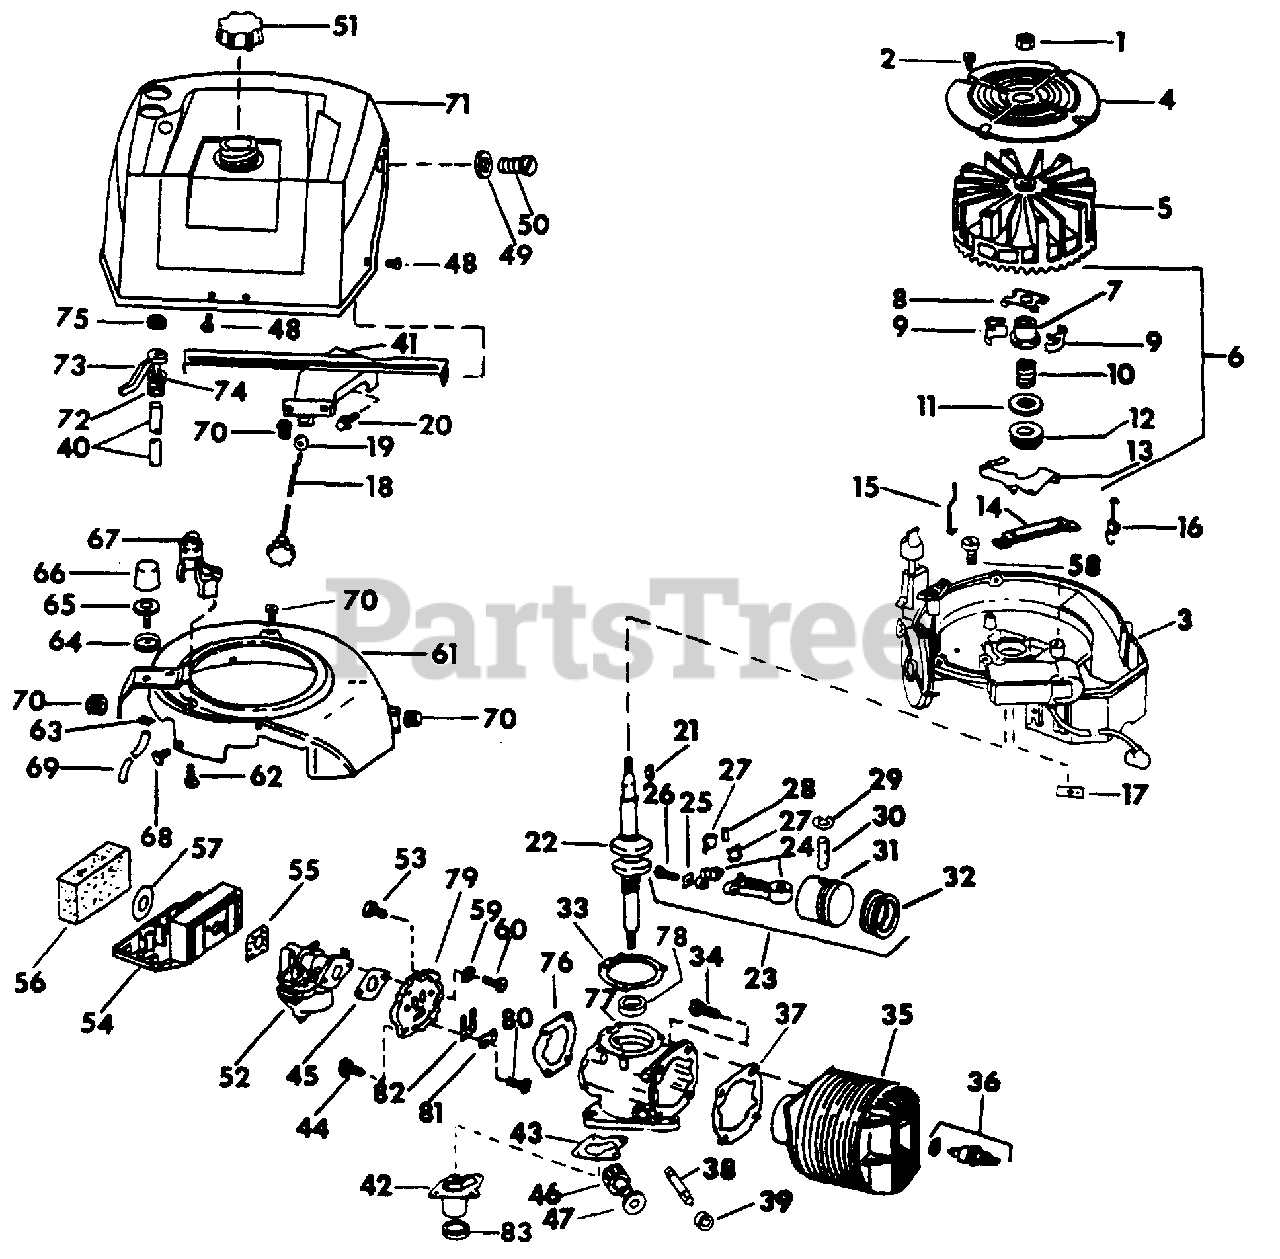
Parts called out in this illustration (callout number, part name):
1	NUT 7/16-20 HEX.
2	SCREW, 10-24 X 1/2 TRUSS-HD REC TAP.
3	MAGNETO ASSY
4	SCREEN, FLYWHEEL
6	GOVERNOR ASSY
7	COLLAR, GOVERNOR
8	YOKE, GOVERNOR
9	WEIGHT, GOVERNOR
10	SPRING, GOVERNOR
11	WASHER, THRUST
12	COLLAR, THRUST
13	LEVER, GOVERNOR
14	BRACKET, GOVERNOR LEVER
15	ROD, GOVERNOR
16	SPRING, VARIABLE SPEED
21	KEY, CRANKSHAFT
23	PISTON & CONNECTING ROD ASSY
24	ROD ASSY, CONNECTING
25	LOCKPLATE, SCREW
26	SCREW, CONNECTING ROD
27	LINER, CONNECTING ROD
28	BEARING SET, NEEDLE
29	RING, RETAINING
32	RING SET, PISTON - 2 RINGS
33	GASKET, CRANKCASE TO ARM PLATE .010
34	SCREW, CYL TO CRANKCASE
36	SPARK PLUG & GASKET
37	GASKET, CYL TO CRANKCASE
39	SEAL, DRIVE OIL
41	BRACKET, SHROUD
43	GASKET CRANKSHAFT
44	SCREW HH REED PLATE TO CRANKCASE
45	GASKET, CARBURETOR
46	GEAR, DRIVESHAFT
47	WASHER, THRUST BRG
48	SCREW, COVER MTG
52	CARBURETOR ASSY
53	SCREW, HH REED PLATE TO CRANKCASE
54	CASE, AIR FILTER
56	ELEMENT, FILTER
58	SCREW, 5/16-18 X 1-1/4 HEX-HD CAP
61	BAFFLE ASSY, AIR
66	BULB, PRIMER
67	BRACKET & EYELET
70	GROMMET, COVER MTG
71	SHROUD, TANK & VALVE ASSY
72	CLIP, SPRING
76	GASKET, REED PLATE
77	CRANKCASE AND SEAL ASSY
79	REED PLATE ASSY
81	PLATE, BACKUP
